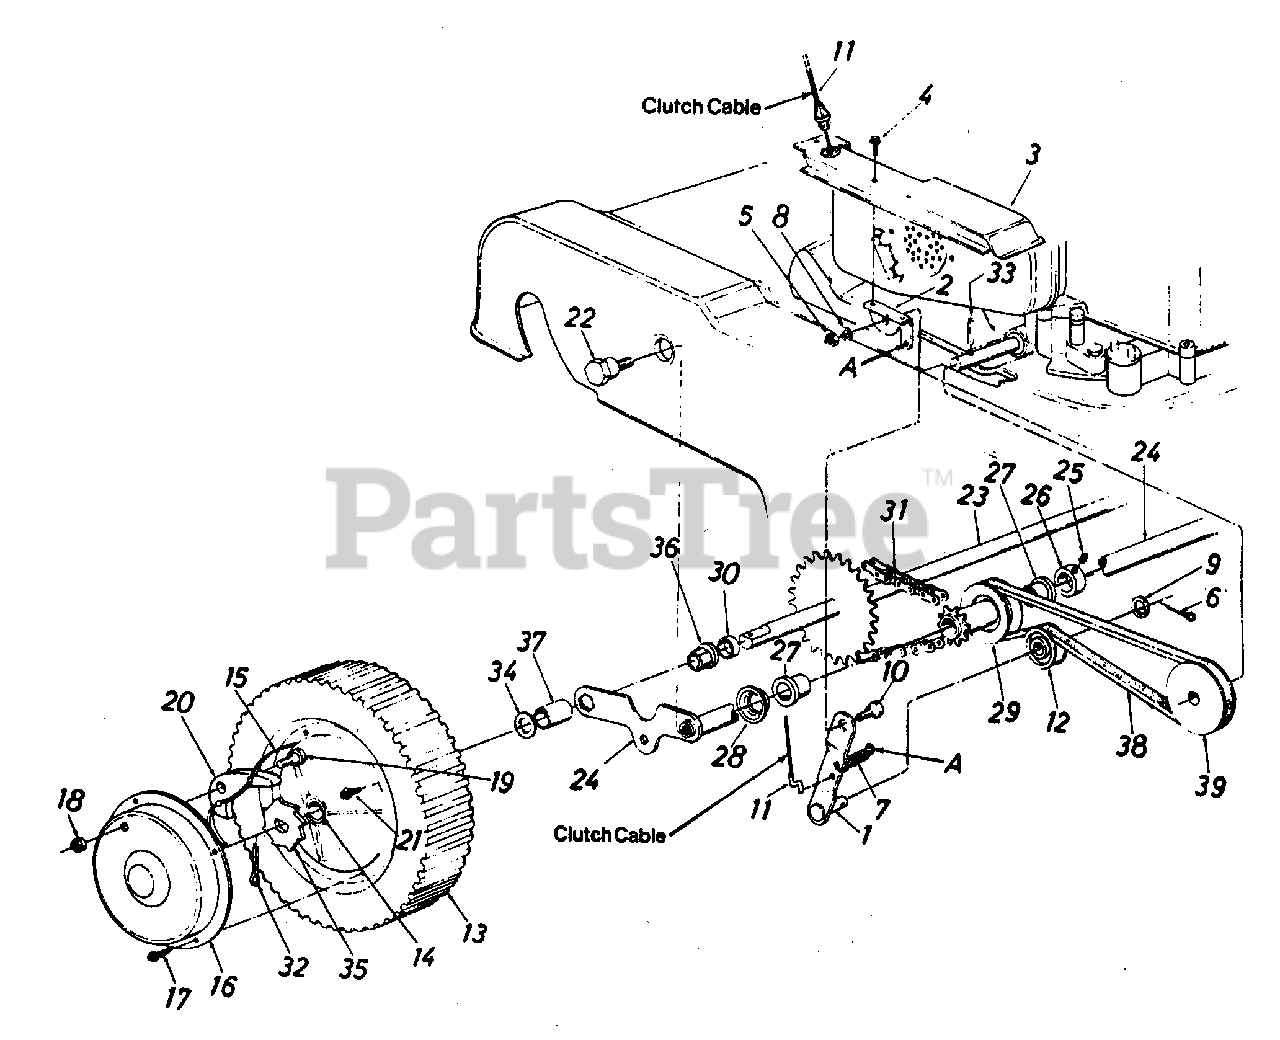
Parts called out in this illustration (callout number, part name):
1	Idler Brkt. Ass'y.
2	Idler Mounting Brkt.
3	Belt Guard
4	Hex Wash. Hd. AB-Tap Scr. 1/4" x.62" Lg.
5	Hex Nut 5/16-18 Thd.*
6	Cotter Pin 1/8" Dia. x 1.00 Lg. *
7	Extension Spring .33" O.D. x 1.12" Lg.
8	L-Wash. 5/16" I.D.*
9	Fl-Wash. .531" I.D. x .930" O.D. x .050
10	Shld. Bolt .375" Dia. x 1.89
11	Clutch Cable-59"
12	Flat Idler 1.62" Dia.
13	Wheel Ass'y. Comp. (Rear)
14	Flange Brg. 1/2" I.D. (Rear)
15	Spring-Nylon
16	Rear Hub Cap
17	Pan Hd. Tap Scr. #12 x .50"
18	Hex Ins. L-Nut 1/4-20 Thd.
19	Shld. Bolt .342" Dia. x .268
20	Pawl
21	Hex Wash. Hd. Tap Scr. #8 x .50" Lg.
22	Shld. Bolt .625" Dia. x .425"
23	Rear Shaft Ass'y.
24	Rear Axle Ass'y.
25	Set Scr. 5/16-18 x .25" Lg. Cup Point
26	Collar 5/8" I.D.
27	Flange Brg. .634" I.D. Plastic
29	Pulley w/9 Tooth Sprocket Ass'y.
30	Spacer .53" I.D. x .75" O.D. x.38" Lg.
31	#48 Chain 1/2" Pitch x 32 Links
32	Cotter Pin 1/8" Dia. x 1.00"*
33	Spring Pin Spir. 3/16" Dia. x 1.50" Lg.
34	Fl-Wash. .531" I.D. x .930" O.D. x .050
35	Ratchet-Rear Wheel
36	Hex Flange Brg. .506" I.D.
37	Spacer.756" I.D. x .89" O.D. x.960" Lg.
38	"V"-Belt 1/2" X 24" Lg.
39	1/2" "V"-Pulley .50" I.D. x 2.52" O.D.
